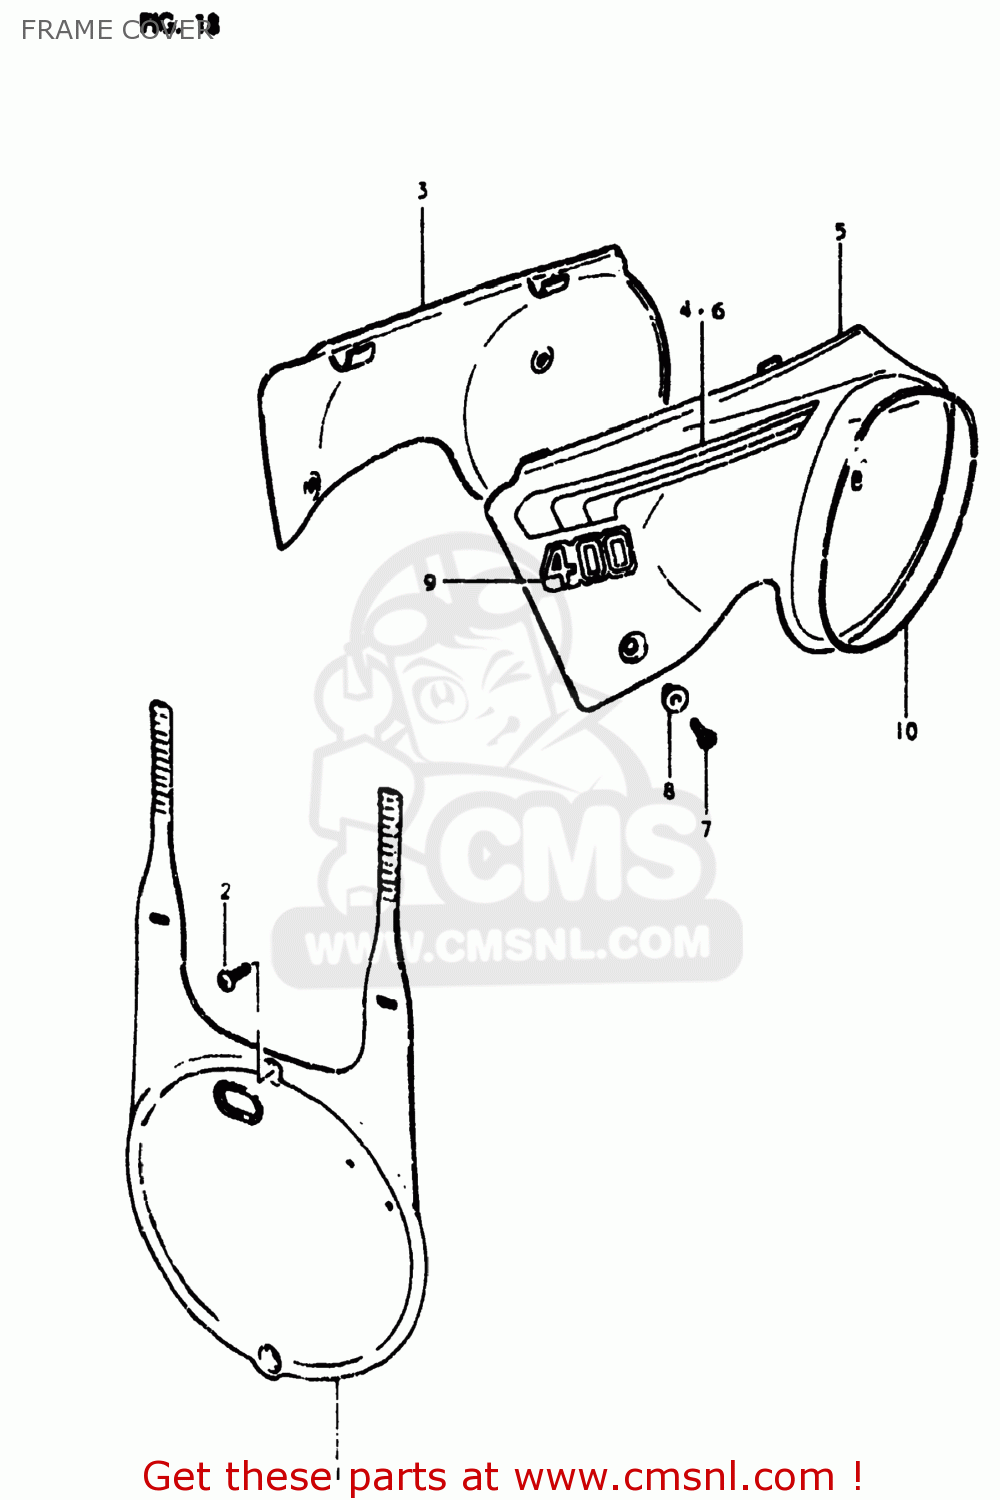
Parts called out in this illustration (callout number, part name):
1	PLATE,FR NUMBER
2	(5X20) CROSS SCREW
3	COVER,FRAME,RIGHT
4	TAPE,FRAME COVER
5	COVER,FRAME,L(YELLOW)
6	TAPE,FRAME COVER
7	SCREW 6X12
8	SPACER
9	EMBLEM
10	TAPE,FRAME COVER
